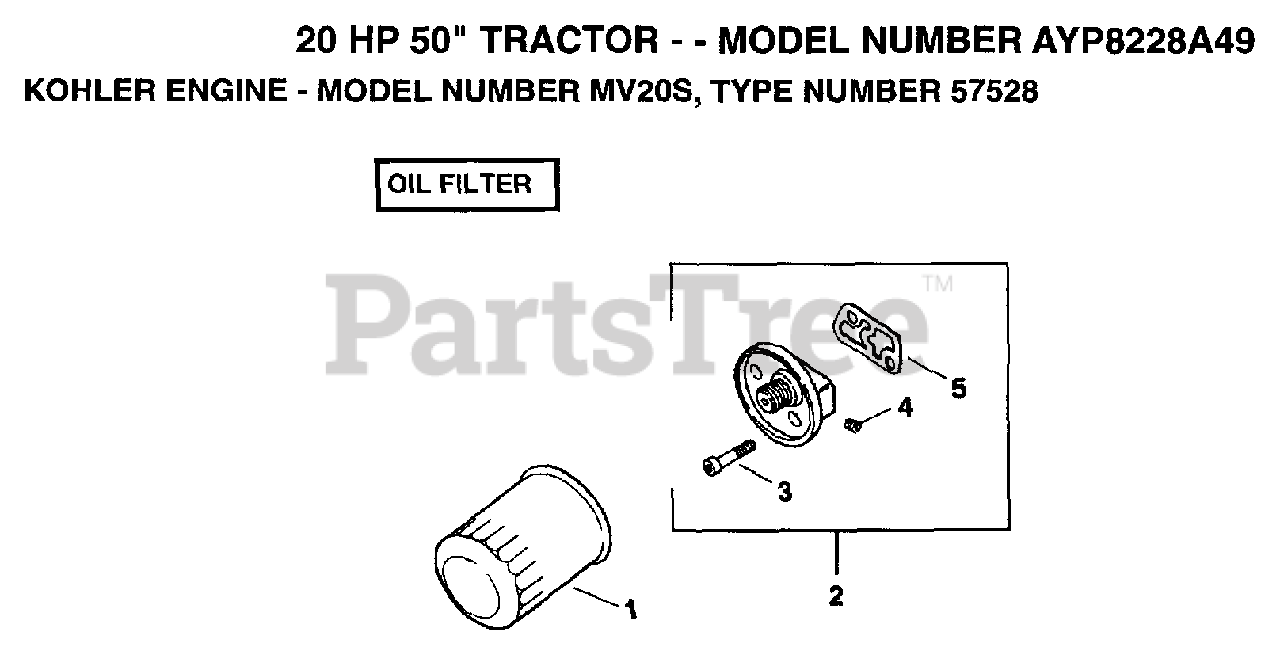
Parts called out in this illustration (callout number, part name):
2	KIT, FILTER ADAPTOR
3	SCREW
4	PLUG
